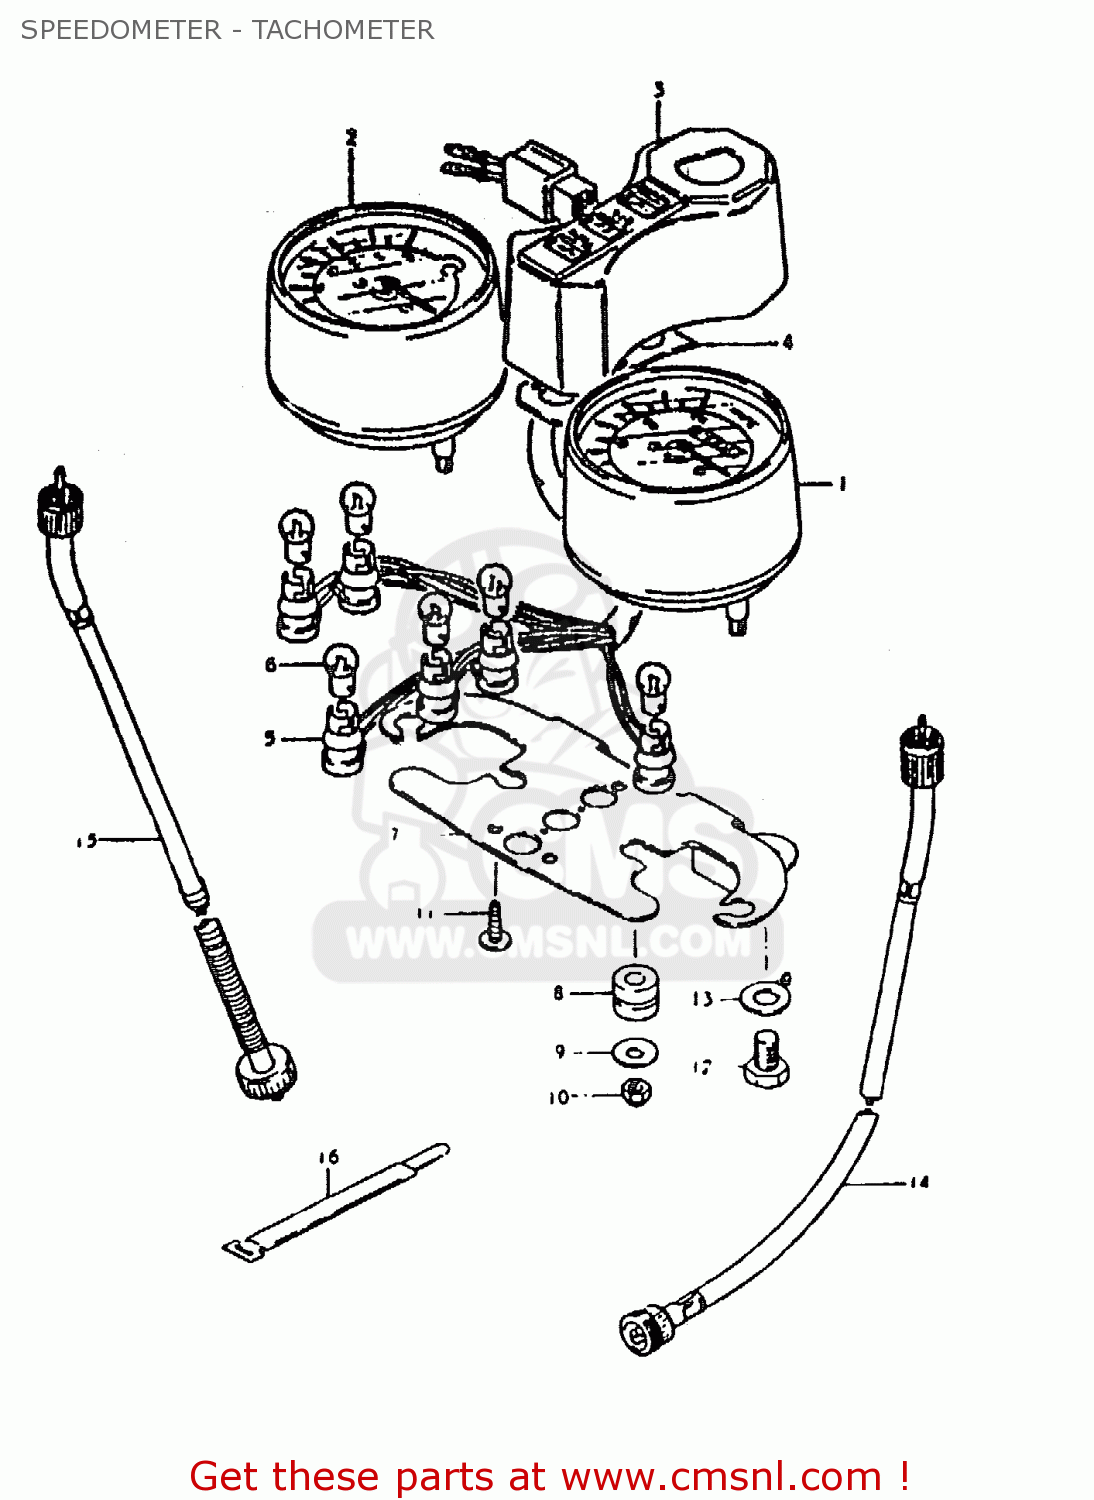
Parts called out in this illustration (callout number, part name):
1	SPEEDOMETER (MILE & KILO)
2	TACHOMETER
3	BOX, PILOT BULB
4	COVER, PILOT BOX
5	SOCKET
6	BULB(6V/3W)
7	BRACKET
8	CUSHION,METER
9	WASHER (5.5X16X1.2)
10	NUT
11	SCREW
12	BOLT 8X12
13	WASHER
14	CABLE, SPEEDOMETER
15	CABLE, TACHOMETER
16	CLAMP
